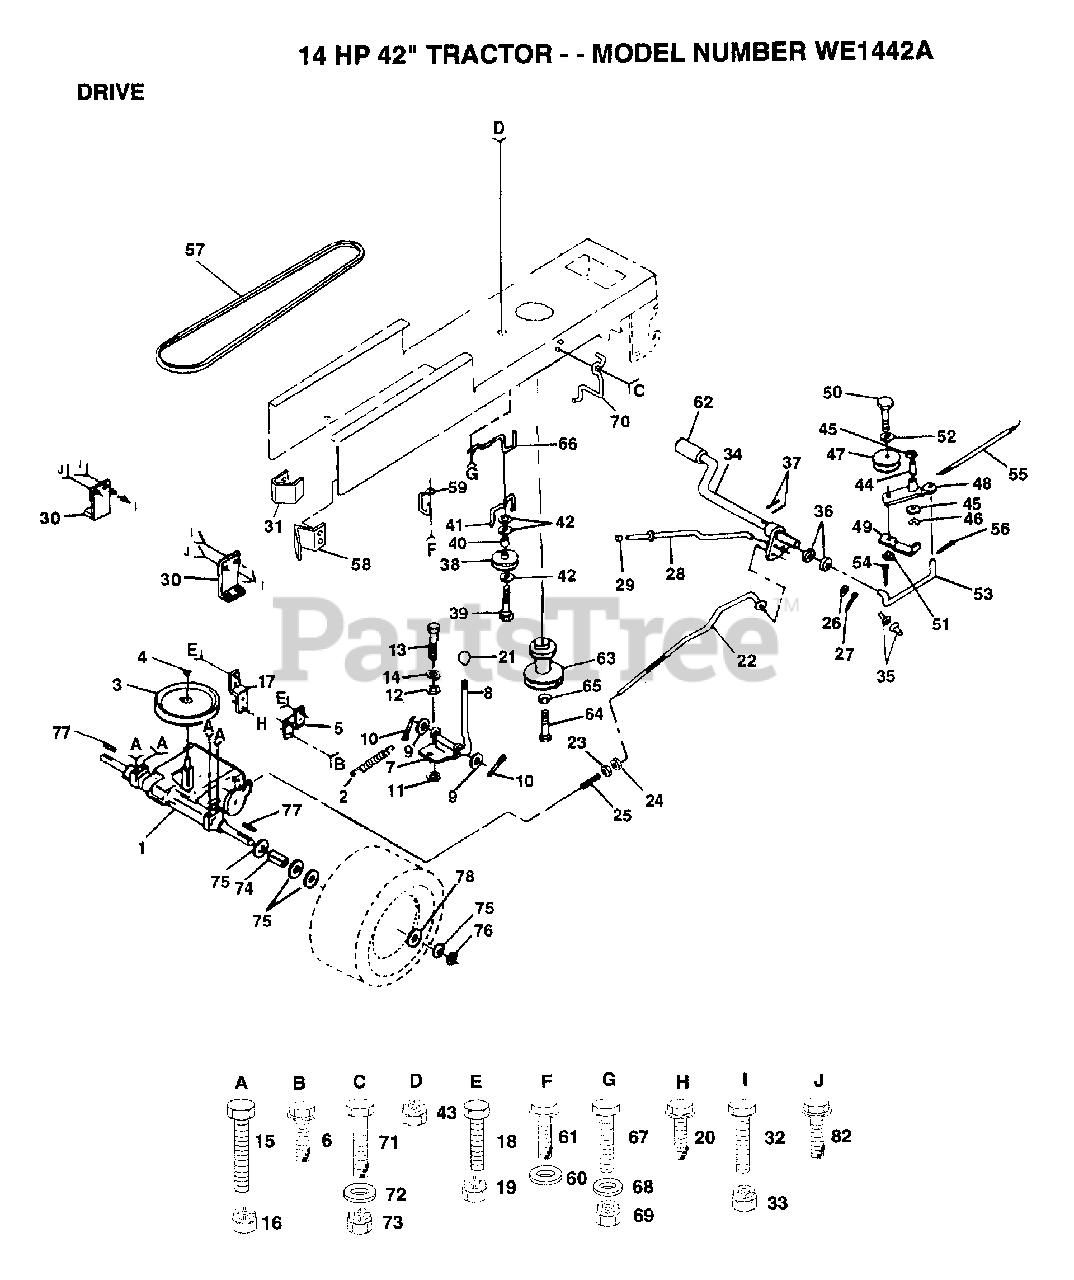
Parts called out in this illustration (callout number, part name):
3	PULLEY TRANS
5	STRAP TORQUE
6	SCREW
8	SHIFT ROD
9	WASHER
10	PIN COTTER 1/8
11	WASH-SHFT PLT LT
12	WASHER LT
14	LOCKWASHER
15	BOLT
17	STRAP TORQUE
20	SCREW
21	KNOB T (1/2-HOLE)
22	BRAKE ROD
23	NUT
24	NUT
25	SPRING ROD LT
26	WASHER
27	COTTER PIN
28	PARKING BRAKE ROD
29	PLUNGER CAP T
30	TRANSAXLE MTG BKT
31	"KEEPER,BELT LH T"
32	BOLT
35	NYLON BEARING
36	WASHER LT
38	PULLEY.IDLER.FLAT
39	BOLT
40	SPACER T
41	BELT KEEPER LT
42	WASHER
44	"LY, BEARING"
45	WASHER LT
46	KLIP RING
48	ARM IDLER
49	RETAIN BELT
52	WASHER
53	"LINK, CLUTCH T"
54	COTTER PIN
55	"SPRING, RETURN LT"
56	COTTER PIN
57	BELT.V.GDRIVE.95
58	"KEEPER,BELT RH T"
60	WASHER
61	SCREW
62	PEDAL COVER T
64	BOLT
65	LOCKWASHER
66	KEEPER.BELT.ENG.L
67	BOLT
68	WASHER
70	KEEPER BELT ENG
71	BOLT
72	WASHER
74	SPACER LT
75	WASHER
76	E-RING LT
77	SQUARE KEY
78	WASHER
82	SCREW
